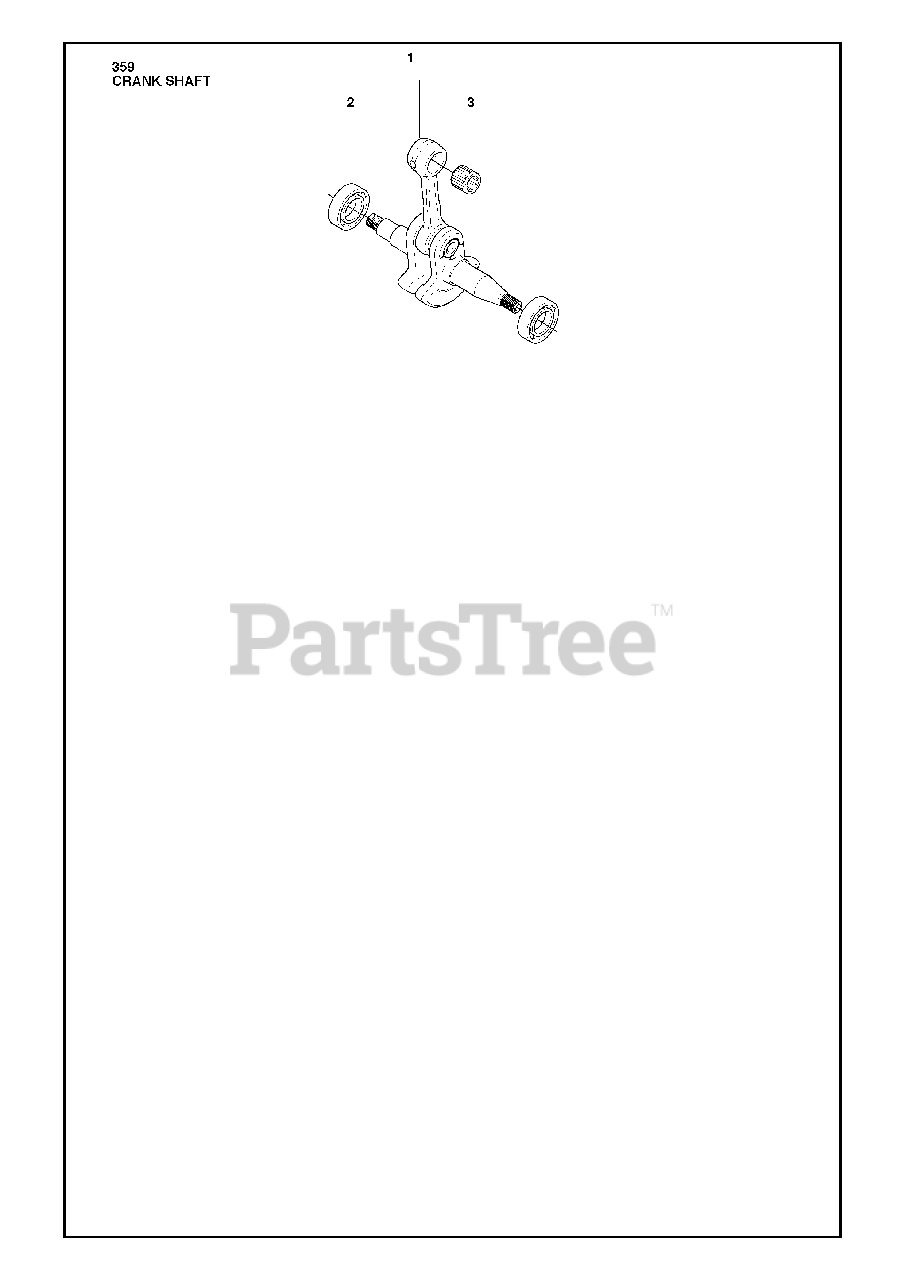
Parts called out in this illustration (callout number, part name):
1	RP CRANKSHAFT
2	BALL BEARING-6202-C3 SKF
3	SUPPORT BUSHING
